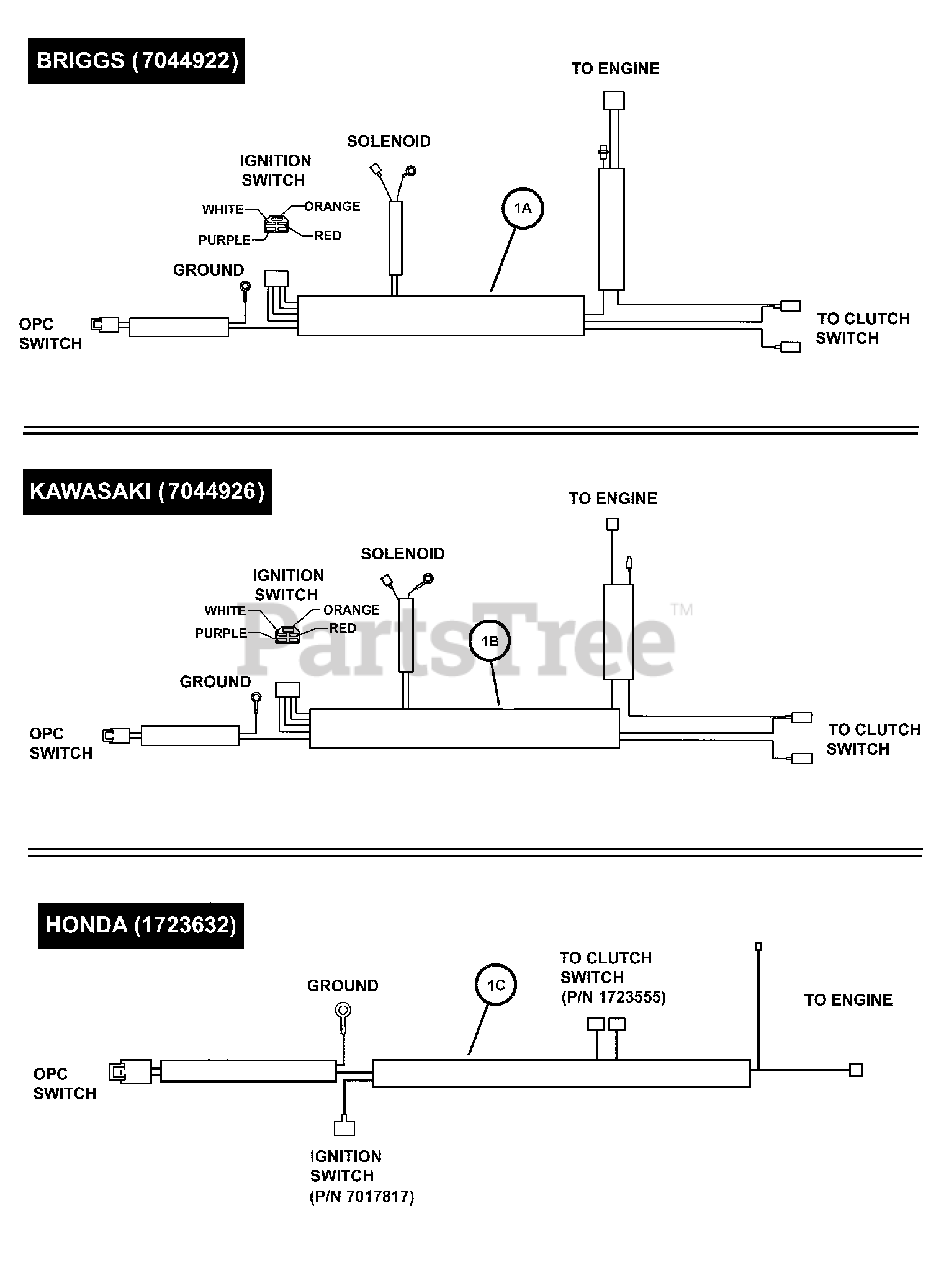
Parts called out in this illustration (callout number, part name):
1A	WIRE HARNESS, Briggs
1B	WIRE HARNESS, Kawasaki
1C	WIRING HARNESS, Honda
